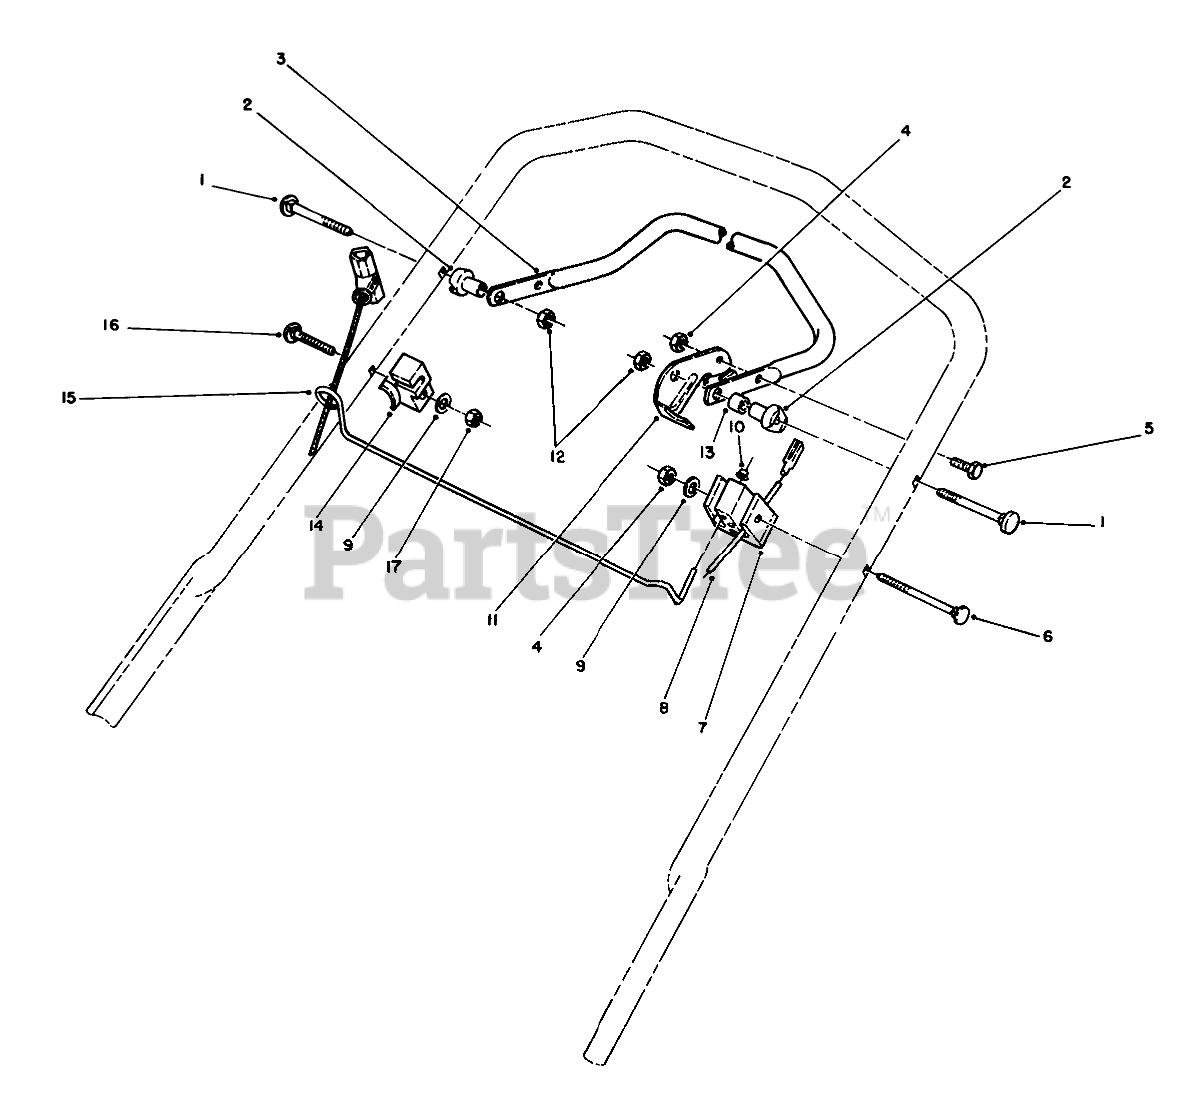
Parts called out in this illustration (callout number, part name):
1	5/16-18 X 2 HNDLE SCREW
2	SPACER-SUPPORT
3	Bar-Control
4	NUT-LOCK, NI
5	SCREW-HH
6	HANDLE SCREW
7	SUPPORT-CABLE
8	BRAKE CABLE
9	WASHER-FLAT
10	NUT-SPEED
11	LEVER-CONTROL
12	NUT-LOCK, NI
13	SPACER-NYLON
14	ROD CATCH
15	ROPE ROD PLATED
16	SCREW-HANDLE
17	NUT-HEX
